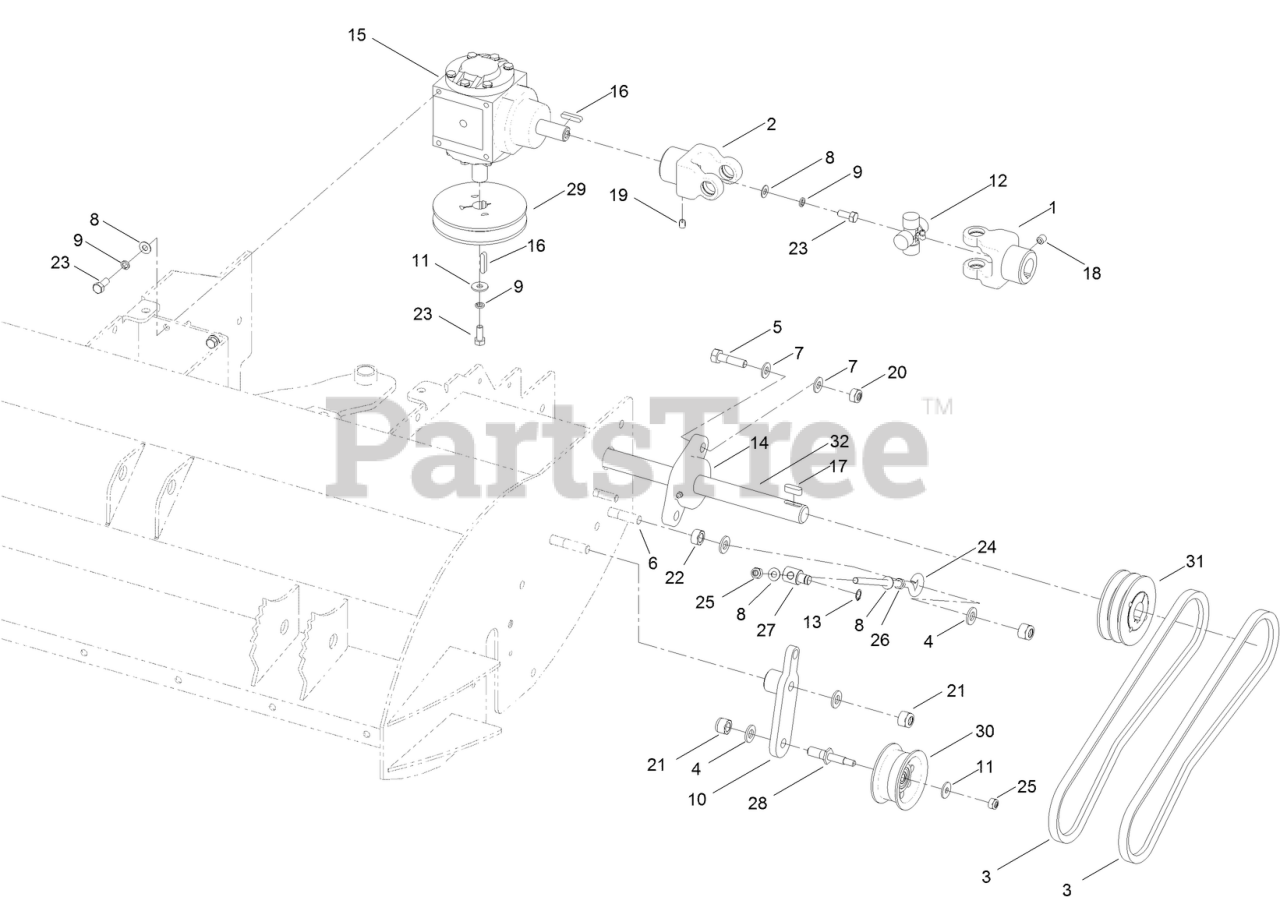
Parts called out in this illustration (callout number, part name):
1	YOKE-PTO
2	YOKE-PTO
4	WASHER-PLAIN
5	BOLT-HH
6	SCREW-HH
7	WASHER-PLAIN
8	WASHER
9	WASHER-SPRING
10	BRACKET-PULLEY, IDLER
11	WASHER
12	JOINT-UNIVERSAL, PTO
13	CIRCLIP-EXTERNAL
14	BEARING-FLANGE
15	GEARBOX
18	SCREW-GRUB, CUP POINT
19	SCREW-GRUB, CUP POINT
20	NUT-HEX, NI
21	NUT-NYLOC
22	NUT-HEX
23	SCREW-HH
24	ROD-EYE, THREADED
25	NUT-HEX, NI
26	NUT-HEX
27	PIVOT-BOSS
28	PIVOT-BRACKET, IDLER
29	PULLEY-GEARBOX
30	PULLEY-IDLER
31	PULLEY-V
32	ROD-DRIVE SHAFT
